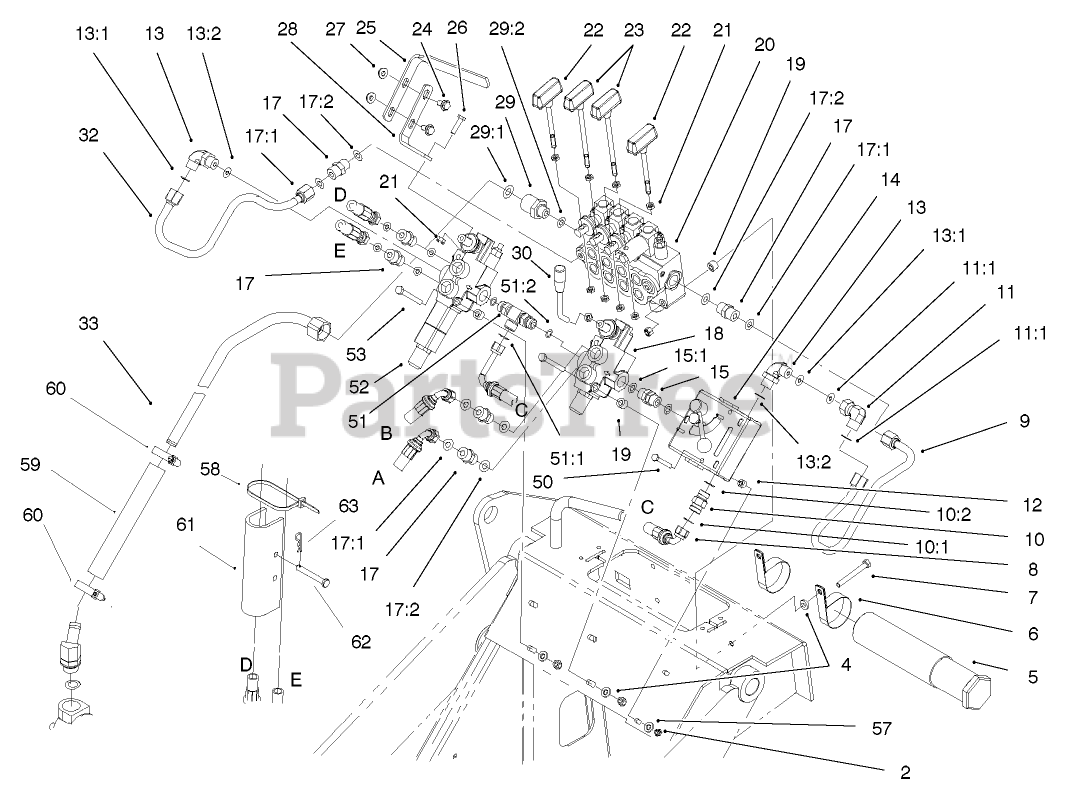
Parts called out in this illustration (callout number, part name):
2	NUT-LOCK, NI
4	WASHER-PLAIN
5	TUBE-MANUAL
6	CLAMP-R
7	SCREW-HH
8	HOSE ASM
9	TUBE-HYD
10	VALVE-CHECK, HYD
10:1	O-RING
10:2	O-RING
11	FITTING-HYD
11:1	O-RING
12	SPACER
13	FITTING-ELBOW-90 DEG
13:1	O-RING
13:2	O-RING
14	HYD VALVE KIT
15	FITTING-THREAD, STRAIGHT
15:1	O-RING
17	FITTING-STRAIGHT
17:1	O-RING
17:2	O-RING
18	VALVE-SELECTOR, HYD
19	SPACER
20	KIT-VALVE, 4-SPOOL, HYD
21	NUT-HEX
22	CYLINDER HANDLE ASM
23	DRIVE HANDLE ASM
24	SCREW-HHF
25	GRIP-CONTROL
26	SCREW-HHF
28	MOUNT-CONTROL
29	FITTING-STR
29:1	O-RING
29:2	O-RING
30	LEVER-VALVE
32	HYD TUBE ASM
33	HYD TUBE ASM
50	SCREW-HH
51	ADAPTER-TEE, ADJUSTABLE
51:1	O-RING
51:2	O-RING
52	VALVE-HYD, AUXILIARY
53	SCREW-HH
57	WASHER-FLAT
58	TIE-CABLE
59	HOSE-HYD
60	CLAMP-HOSE
61	LOCK-CYLINDER
62	PIN-CLEVIS
63	PIN-HAIR
